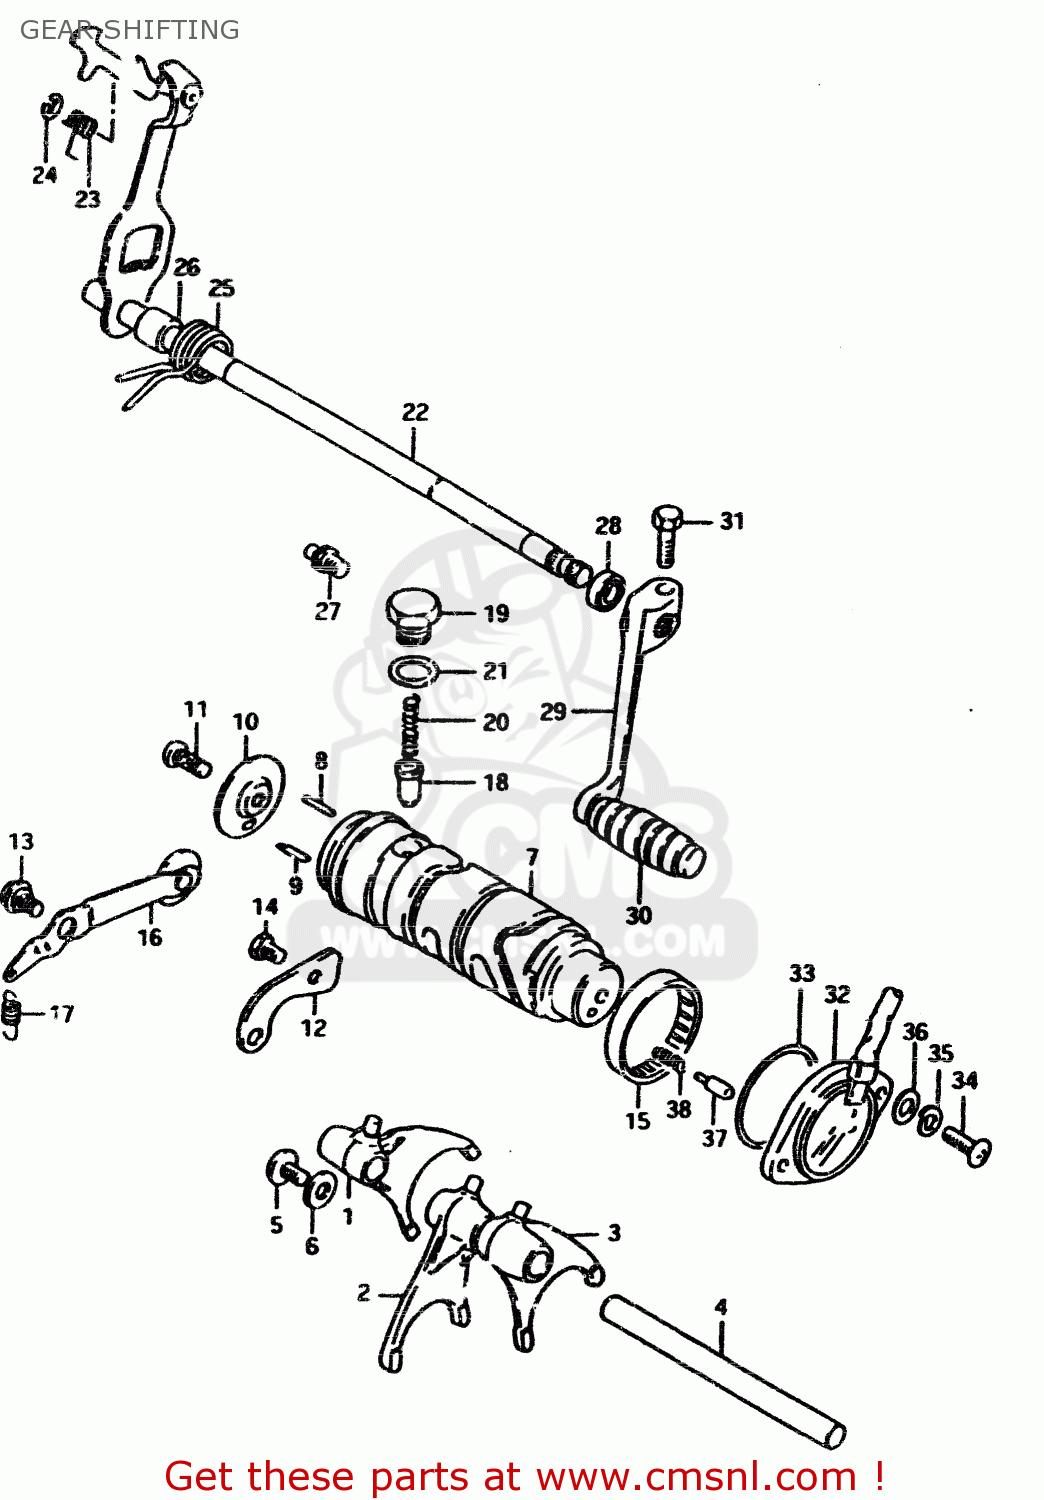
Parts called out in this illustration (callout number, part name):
1	FORK,GEAR SHIFT NO.1
2	FORK,GEAR SHIFT NO.2
3	FORK,GEAR SHIFT NO.2
4	SHAFT,GEAR SHIFT FORK
5	SCREW
6	WASHER
7	CAM,GEAR SHIFT
8	PIN(4X18.5)
9	PIN
10	RETAINER,GEAR SHIFT CAM DR PIN
11	SCREW
12	GUIDE,GEAR SHIFTING CABLE
13	BOLT
14	BOLT, UPPER
15	BEARING(40X47X12)
16	STOPPER,GEAR SHIFT CAM NO.1
17	SPRING
18	STOPPER,GEAR SHIFT CAM NO.2
19	HOLDER,GEAR SHIFT CAM STOP SPR
20	SPRING
21	GASKET(14X19.2X2) (NAS)
22	SHAFT,GEAR SHIFT
23	SPRING
24	E RING
25	SPRING
26	SPACER(12X20X15.3)
27	STOPPER,GEAR SHIFT CAM
28	OIL SEAL
29	LEVER ASSEMBLY,GEAR SHIFTING
30	RUBBER,GEAR SHIFT PEDAL
31	BOLT
32	BASE ASSEMBLY,NEUTRAL SWITCH TERMINAL
33	O-RING (D:2.4 ID:26.2)
34	SCREW 5X20
35	LOCK WASHER
36	WASHER
37	PIN(5X15.5)
38	SPRING
